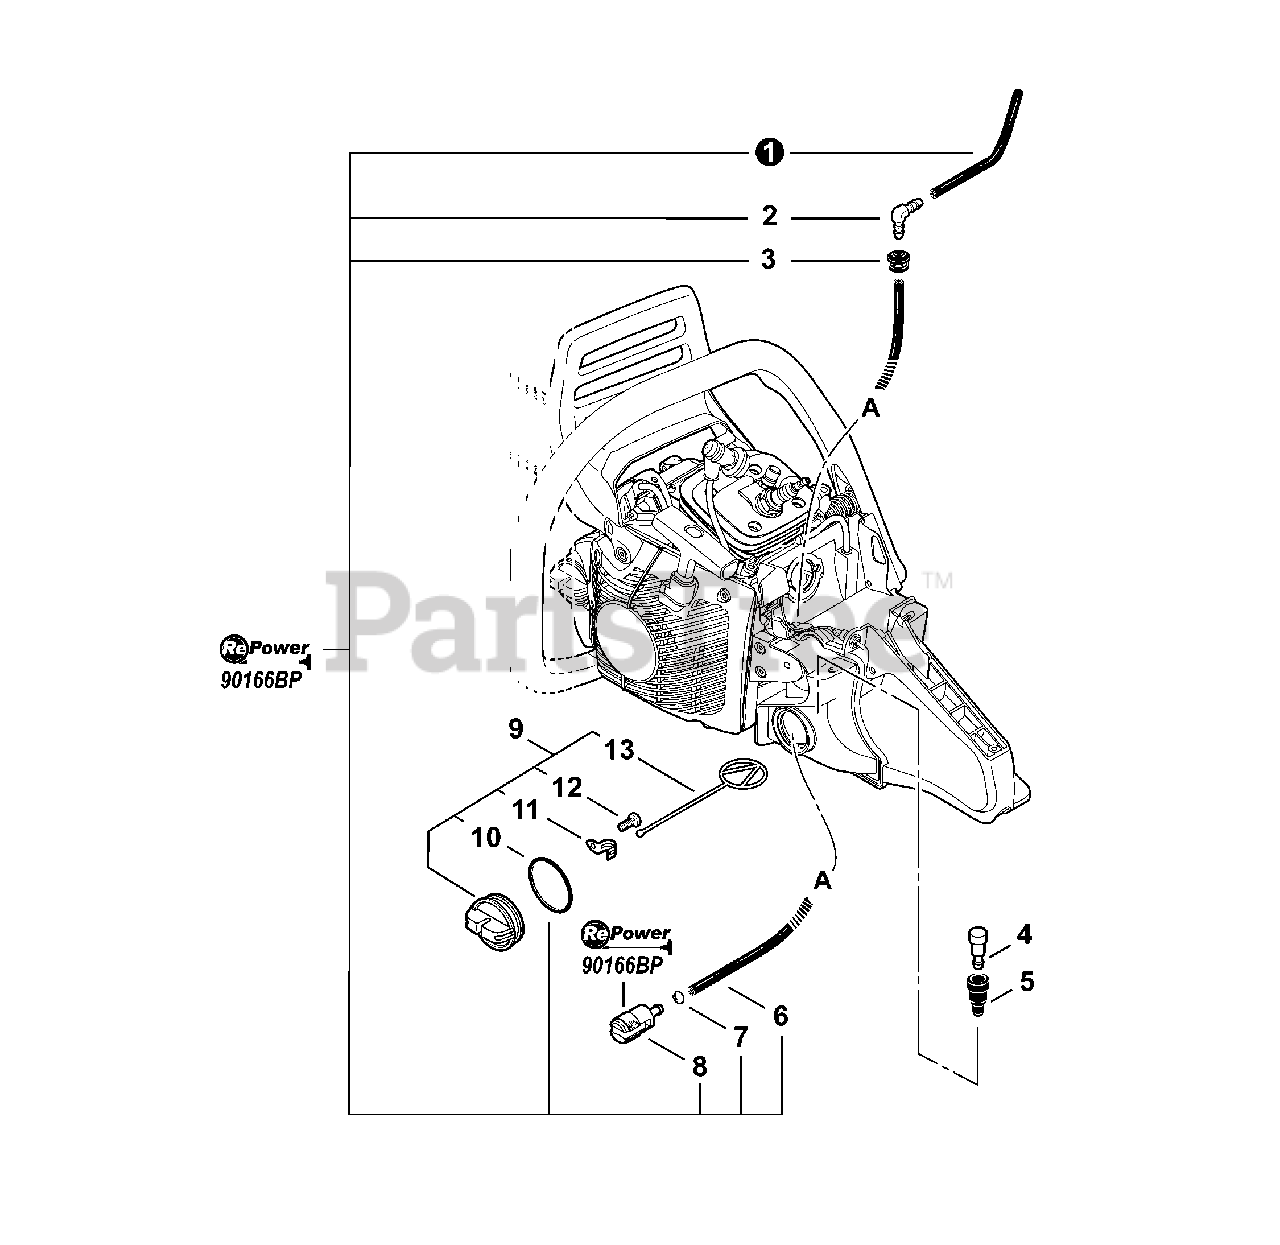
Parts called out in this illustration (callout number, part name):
1	PIPE, FUEL 3×6×135
2	CONNECTOR, PIPE
3	GROMMET
4	VENT ASSY
5	GROMMET, VENT
6	PIPE, FUEL 3×5×120 BLACK
7	CLIP Ø6
8	FILTER, FUEL
9	CAP ASSY, FUEL
10	O-RING 29
11	RETAINER, CONNECTOR
12	SCREW, TAPPING 3×8
13	CONNECTOR, CAP L= 60 MM
